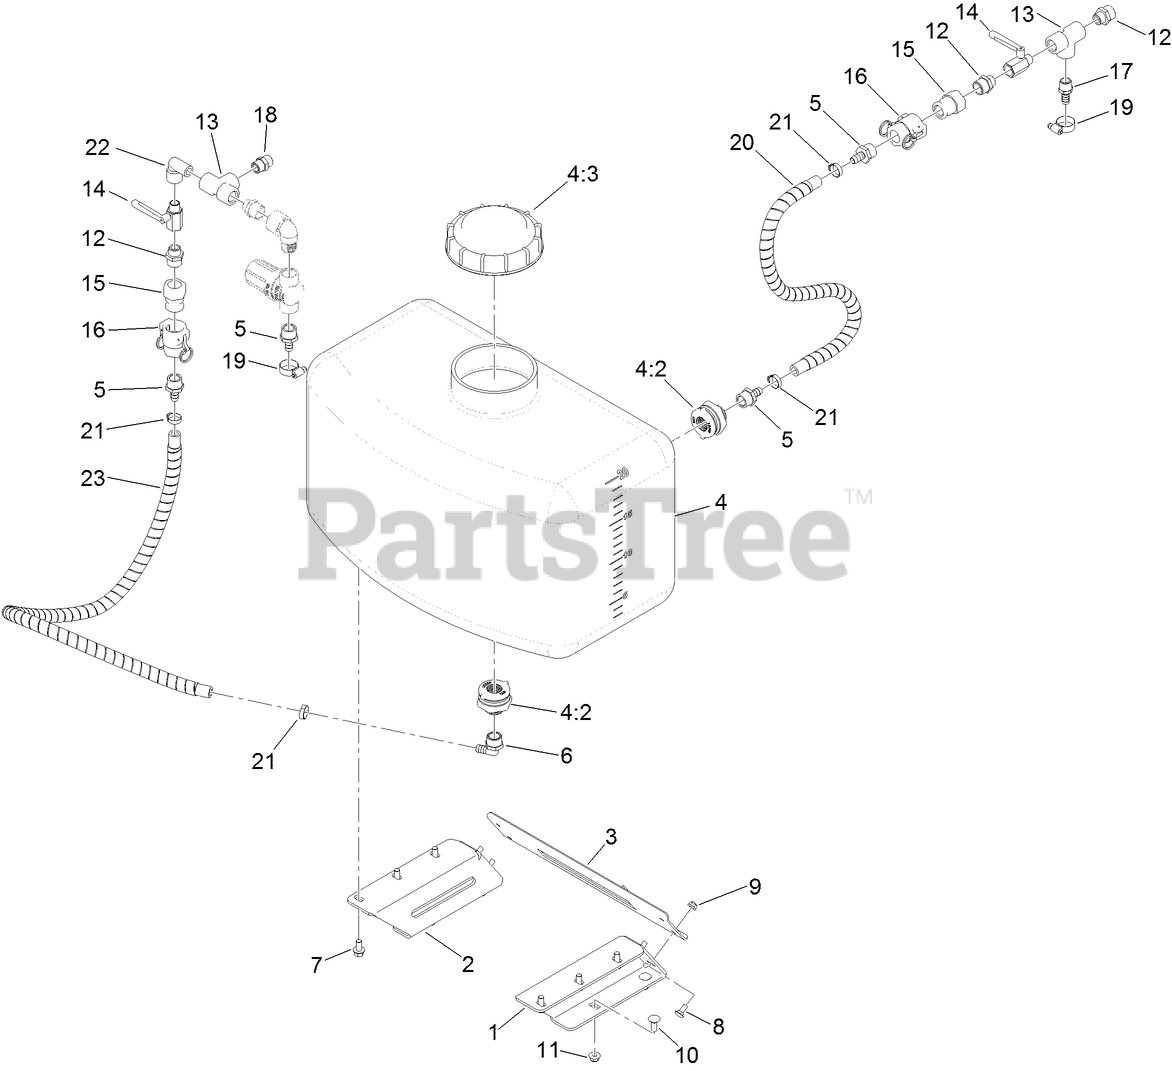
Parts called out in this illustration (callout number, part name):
1	MOUNT-TANK, LT AUX
2	MOUNT-TANK, RT AUX
3	BASE, FRONT, 20GAL, J36
4	ASM-TANK, 20 GAL
4:2	FITTING-BULKHEAD
4:3	CAP-TANK, SPRAY
5	FITTING-STRAIGHT
6	FITTING-ELBOW, 90
7	SCREW-HHF
8	SCREW-CARR
9	NUT-HEX FLANGE
10	SCREW-CARR
11	NUT-HEX FLANGE
12	FITTING-NIPPLE
14	VALVE-CHROME, 1/2
15	ADAPTER-MALE
16	COUPLER-FEMALE
17	FITTING-HOSEBARB
18	FITTING-NIPPLE
19	CLAMP-HOSE
20	HOSE-SPRAY, WRAPPED
21	CLAMP-OETIKER, 167
22	FITTING-ELBOW, 90 DEG
23	HOSE-SPRAY WRAPPED
